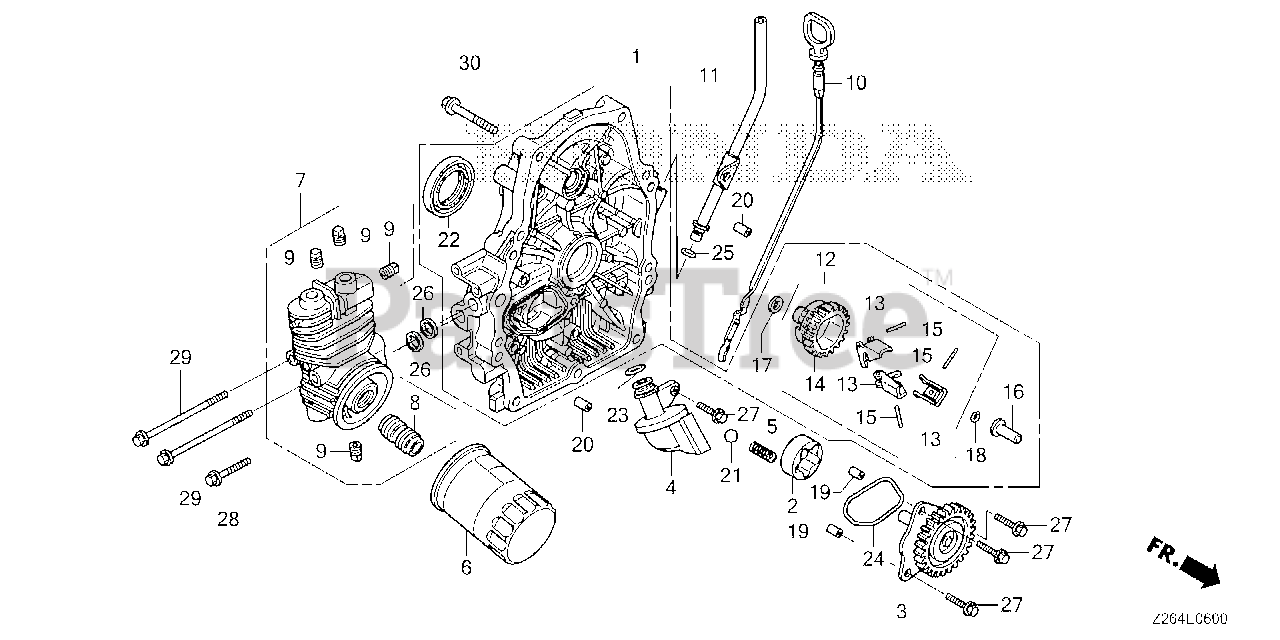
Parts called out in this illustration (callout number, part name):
1	COVER ASSY., CRANKCASE (NOT AVAILABLE)
2	ROTOR, OIL PUMP (OUTER)
3	GEAR, OIL PUMP
4	STRAINER, OIL
5	SPRING, RELIEF VALVE
6	FILTER, OIL (FILTECH TOYO ROKI) (SOLD INDIVIDUALLY)
6	FILTER, OIL
7	BASE, OIL FILTER
8	HOLDER, OIL FILTER
9	BOLT, SEALING
10	GAUGE, OIL LEVEL
11	PIPE, OIL LEVEL
12	GOVERNOR ASSY.
13	WEIGHT, GOVERNOR
14	HOLDER, GOVERNOR WEIGHT
15	PIN, GOVERNOR WEIGHT
16	SLIDER, GOVERNOR
17	WASHER (6X16)
18	CLIP, GOVERNOR HOLDER
19	PIN, DOWEL (8X10)
20	PIN, DOWEL (8X14)
21	BALL, STEEL (#15) (15/32)
22	OIL SEAL (38X58X9)
23	O-RING (14.8X2.4)
24	O-RING, OIL PUMP
25	O-RING (8.8X1.9)
26	GASKET, OIL PASSAGE
27	BOLT, FLANGE (6X20)
28	BOLT, FLANGE (6X28)
29	BOLT, FLANGE (6X90)
30	BOLT, FLANGE (8X45)
